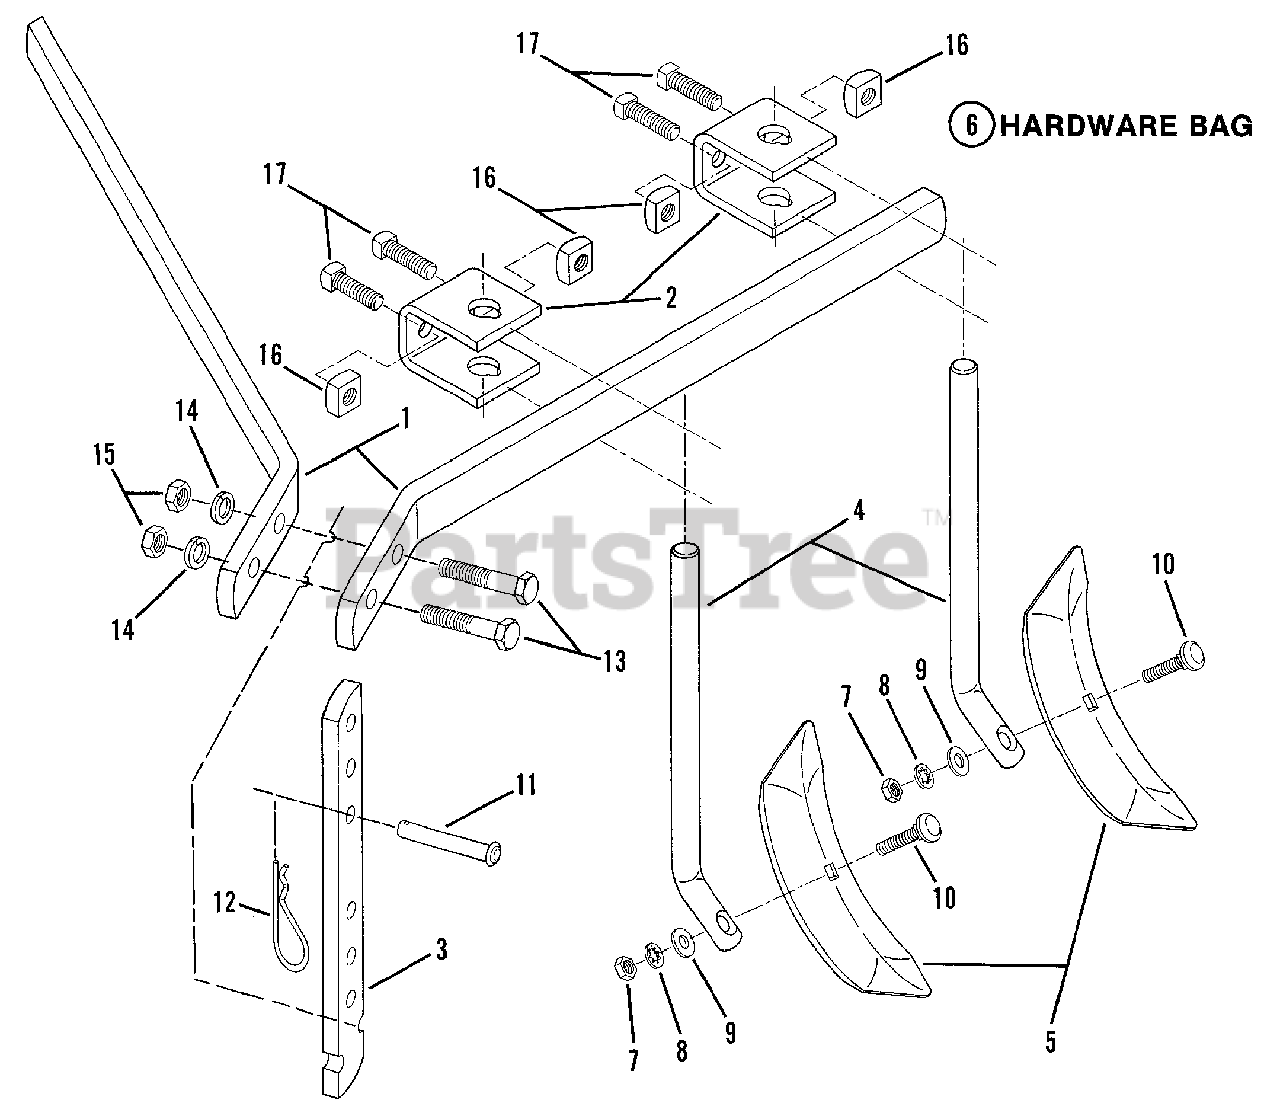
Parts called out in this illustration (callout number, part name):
1	(NLA) TOOL BAR
2	CLAMP
3	(NLA) BEAM, Cultivator
4	SHANK, Cultivator 11.25"x.75"
5	SHOVEL, Double Point
7	NUT, 3/8-16 Hex
8	WASHER, 3/8 Internal-Tooth Lock
9	WASHER, 3/8" Flat
10	BOLT, 3/8-16x1-1/2" Carriage
11	PIN, Clevis, 3/8x2-9/16"
12	PIN, Hair
13	SCREW, 1/2-13x2" Hex Head Cap
14	WASHER, 1/2 Split Lock
15	NUT, 1/2-13 Hex
16	NUT, 1/2-13 Square
17	SCREW, 1/2-13x1-1/4" Square Head Set
